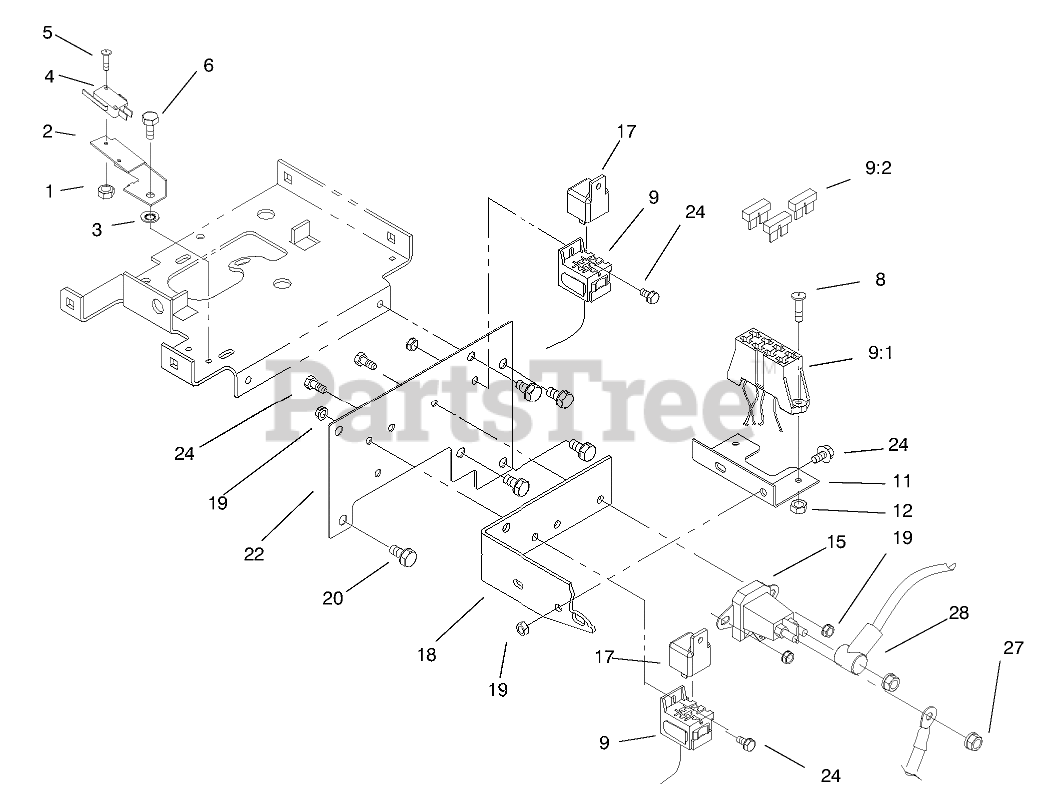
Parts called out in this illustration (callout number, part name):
1	NUT-HEX
2	BRACKET-SWITCH
4	SWITCH
5	SCREW-PPH
6	SCREW-HWH
8	SCREW-PAN
9	HARNESS - WIRE, MAIN
9:1	FUSE-HOLDER 4 WAY
9:2	FUSE-10 AMP
9:2	FUSE-BLADE, 25 AMP
9:2	FUSE-BLADE, 20 AMP
9:2	FUSE-30 AMP
11	FUSE HOLDER
12	Nut
15	Solenoid
17	RELAY
18	BRACKET-BELT (BLACK)
19	NUT-LOCK, NI
20	Bolt
22	PLATE-FRONT HOODS (BLACK)
23	CABLE
24	SCREW-HHF
27	NUT-KEPS
28	CABLE
